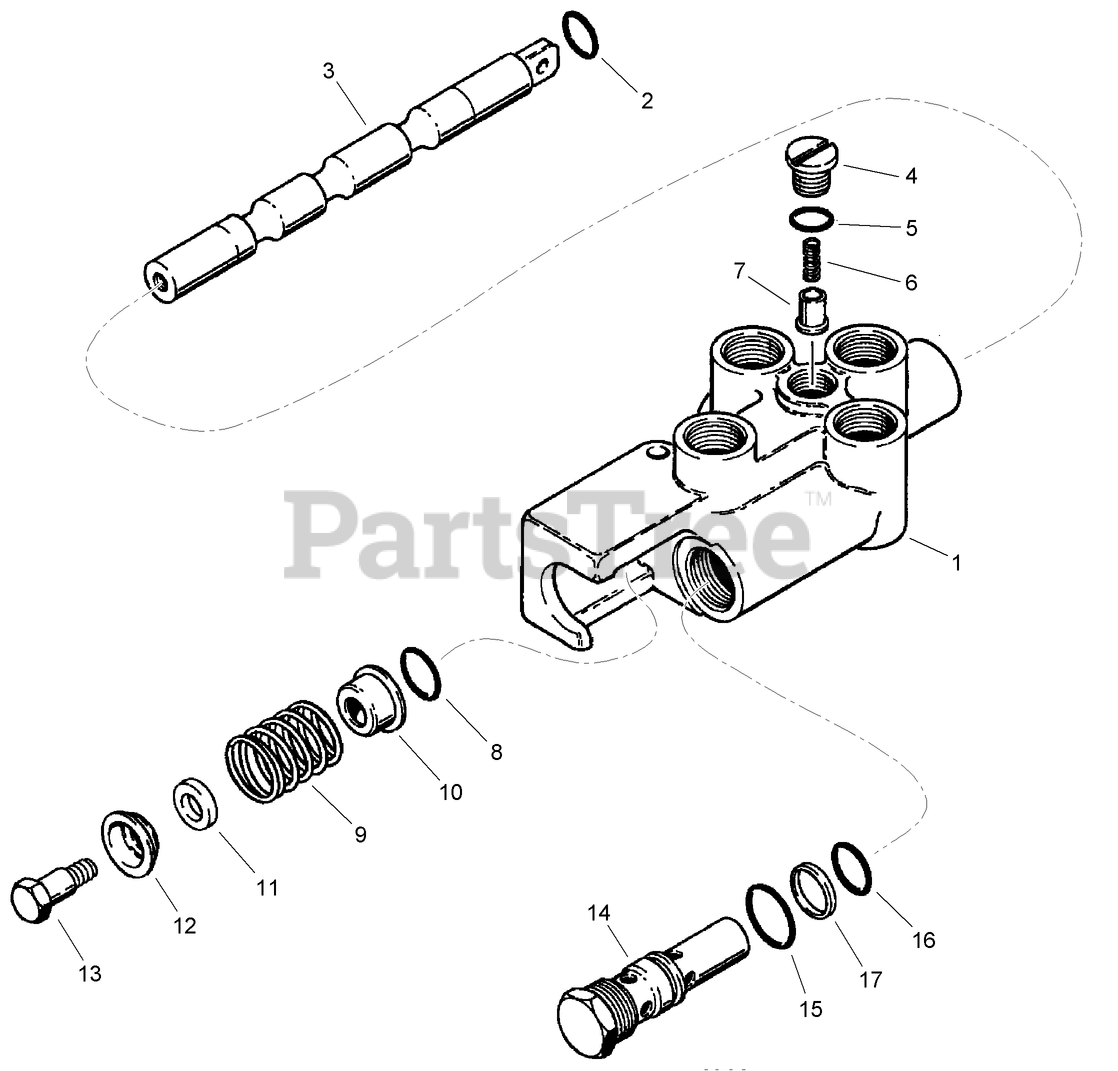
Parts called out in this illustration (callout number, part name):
1	BODY - Control Valve
2	O-RING - Spool
3	SPOOL - Valve
4	PLUG - Load Check
5	O-RING - 1/2 ID x 3/32 inch Wide
6	SPRING - Load Check Valve
7	POPPET - Load Check Valve
8	O-RING - Plug End
9	SPRING - Centering, Spool
10	RETAINER - Spring, Inner
11	WASHER - Special, 4 mm (5/32 inch) Thick
12	SEAT - Spring, Outer
13	BOLT - Hex, Special, Special, Spool
14	VALVE - Relief, Control Valve
15	O-RING-3/4 ID x 3/32 inch wide
16	O-RING
17	RING - Backup, Plug O-Ring
